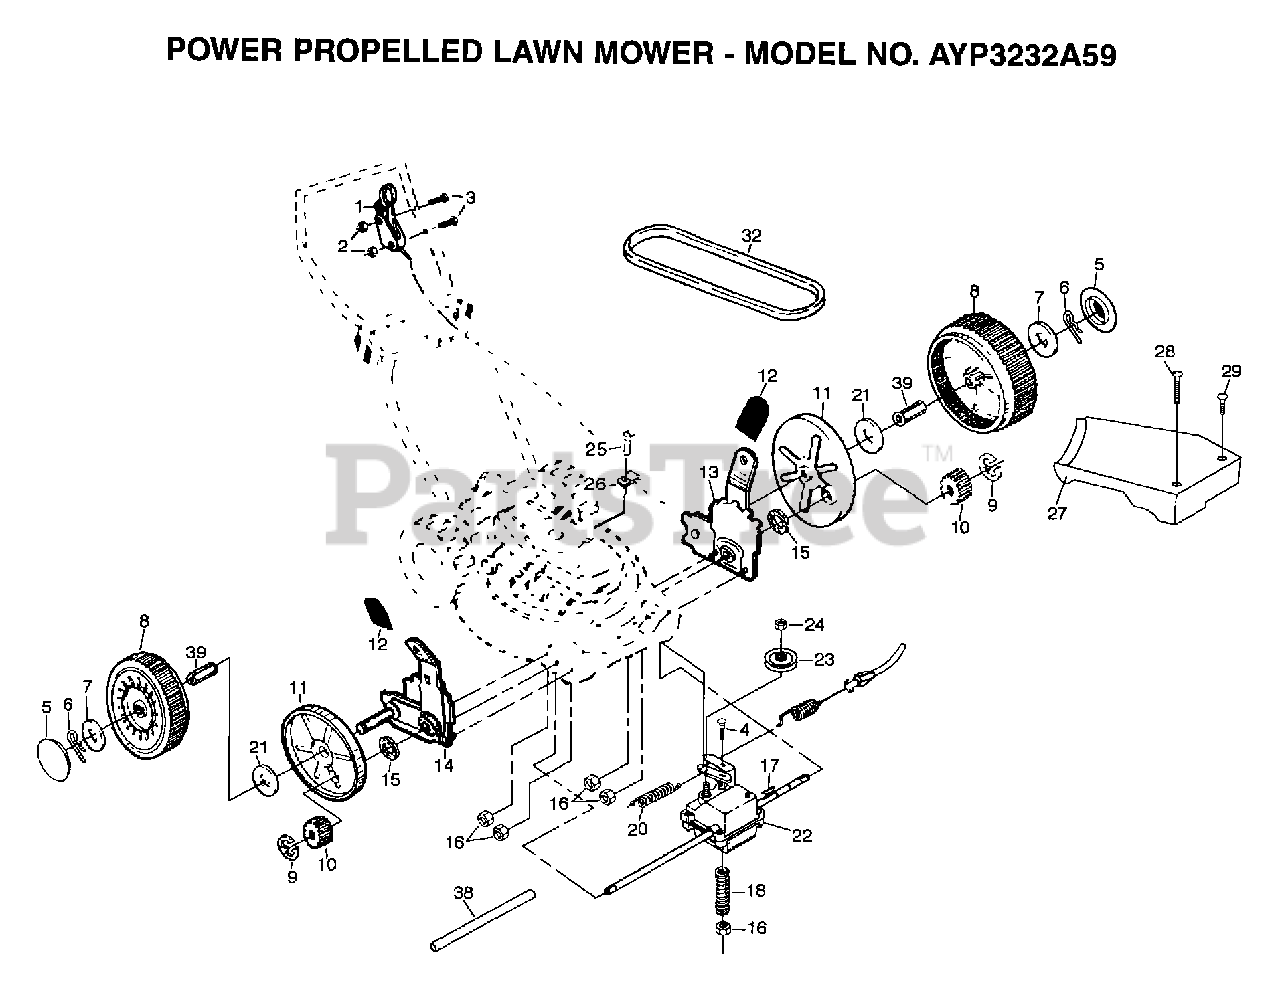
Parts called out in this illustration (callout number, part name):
1	CONTROL.DRIVE
2	LOCKNUT
3	SCREW
4	BOLT.1/4-20X2.0
5	HUB CAP
6	RETAINER CLIP PM
7	WASHER
8	WHEEL.8X2.LP.PR
9	E-RING.7/16.RE.
10	PINION.GEAR
11	DUST SHROUD PM
12	KNOB PM
15	WASHER PM
17	HI PRO KEY
18	SPRING.TENSION
20	SPRING
21	WASHER FLUT
23	PULLEY.DRIVEN
24	LOCKNUT
25	TAPPING SCREW
26	GUIDE CLIP PM
27	COVER DRIVE BLK
38	DRV SHAFT TUBE PM
39	BUSHING.HEX
